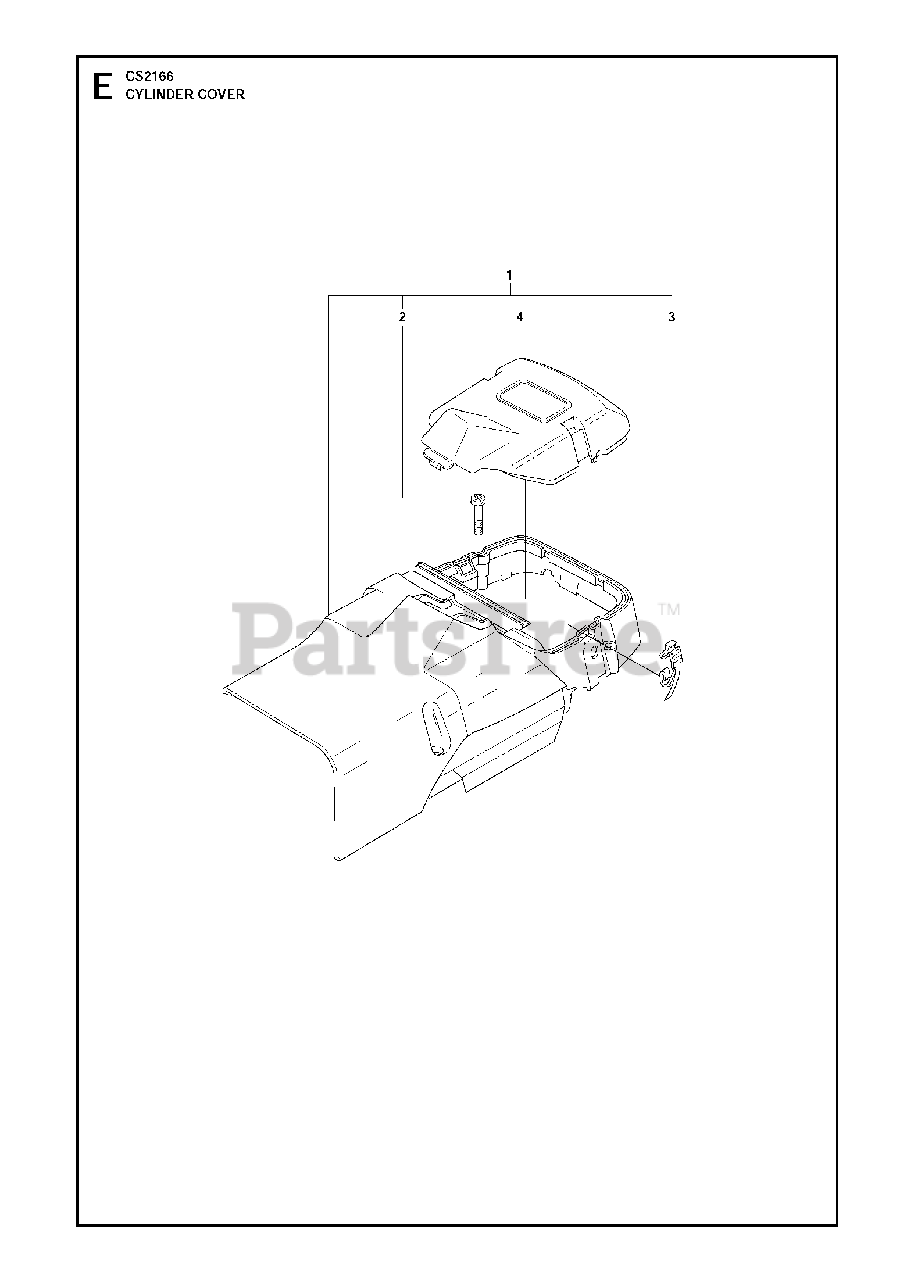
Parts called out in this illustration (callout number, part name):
1	CYLINDER COVER ASSY
2	SCREW
3	CLIP
4	FILTERCOVER
